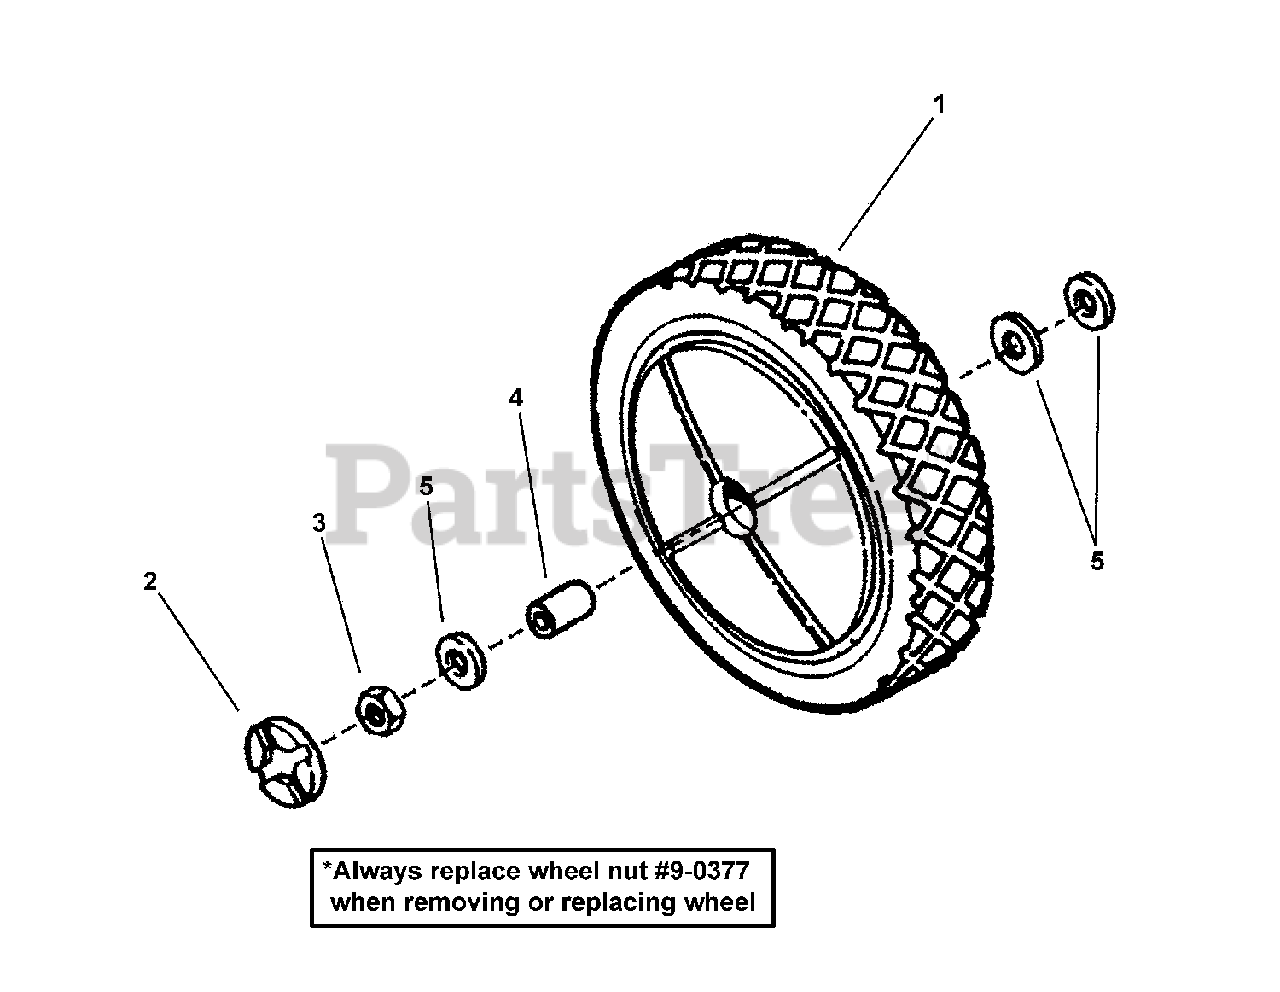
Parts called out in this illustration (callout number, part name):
1	WHEEL, 8 x 1.75 Plastic
2	PLUG, Wheel
3	NUT, 7/16-20 Hex Center Lock Jam
4	BUSHING, Axle
5	WASHER, 7/16" Flat
